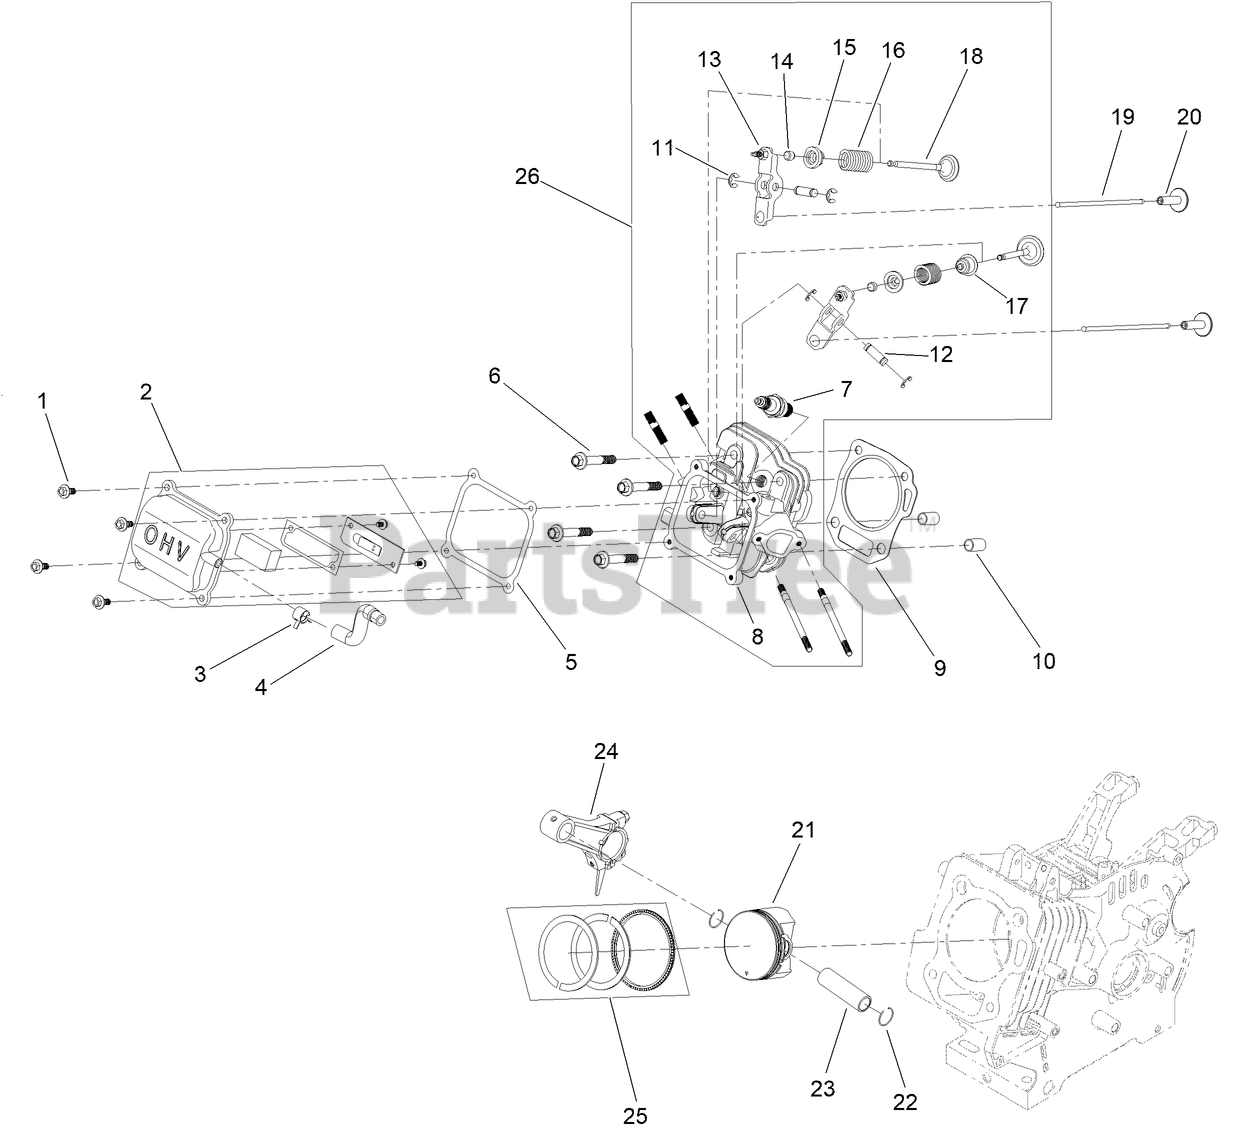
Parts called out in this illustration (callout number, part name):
1	SCREW-HHF
2	VALVE COVER ASM
3	CLAMP-HOSE
4	TUBE-BREATHER
5	GASKET-COVER, VALVE
6	SCREW-FLANGE
7	SPARK PLUG
8	HEAD-CYLINDER
9	GASKET-HEAD
10	PIN-DOWEL
11	E-CLIP
12	PIN-ARM, ROCKER
13	ROCKER ARM ASM
14	ROTATOR-VALVE
15	RETAINER-SPRING, VALVE
16	SPRING-VALVE
17	SEAL-STEM, VALVE
18	SET-VALVE
19	ROD-PUSH
20	TAPPET-VALVE
21	PISTON
22	CLIP-PIN, PISTON
23	PIN-PISTON
24	CONNECTING ROD ASM
25	SET-RING, PISTON
26	COMPLETE HEAD ASM
